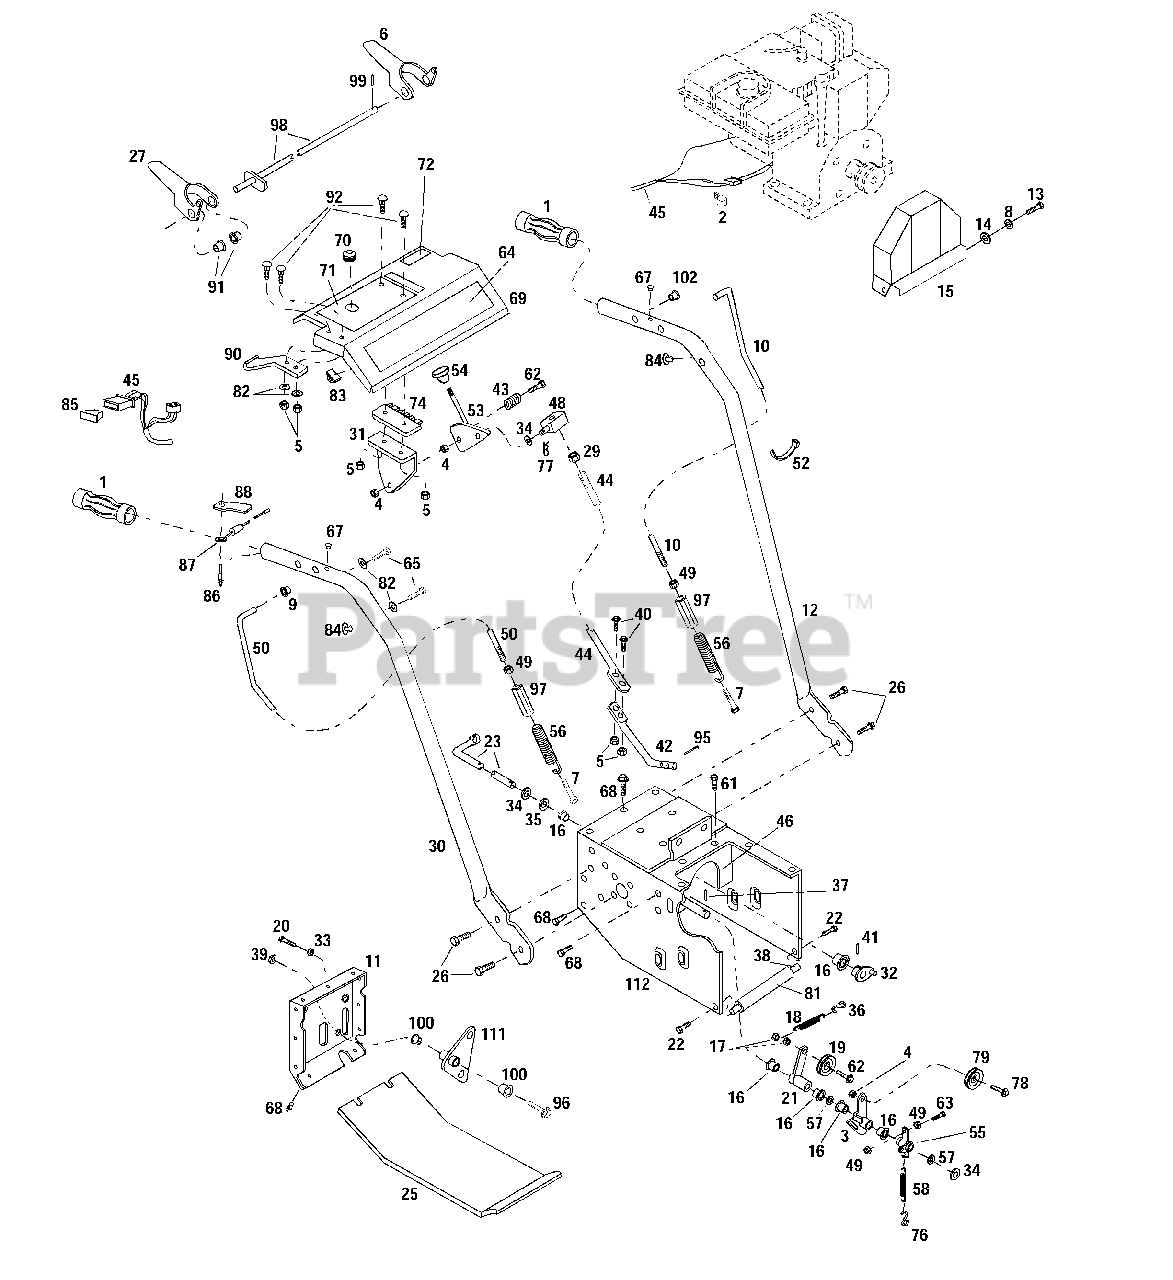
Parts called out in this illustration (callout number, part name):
1	Handle Grip
2	J-Clamp
3	Idler Arm
4	Lock Nut, 3/8-16
5	Lock Nut, 1/4-20
6	Left Control Handle
7	Fillister-Head Bolt, 5/16-18 x 1
8	Lock Washer, 5/16
9	Push Nut
10	Wheel Drive Clutch Rod
11	Back Plate
12	Left Handle Bar
13	Hex Head Bolt, 5/16-18 x 3/4
14	Flat Washer, 5/16
15	Belt Cover
17	Self-Locking Jam Nut, 3/8-16
18	Extension Spring
19	Idler Pulley
20	Flange Bolt, 5/16-18 x 1-3/4
21	Idler Arm
22	Flange Bolt, 5/16-18 x 3/4
23	Control Arm
25	Bottom Cover
26	Flange Bolt, 3/8-16 x 3/4
27	Right Control Handle
29	Hex Nut, 3/8-16
30	Right Handle Bar
31	Control Bracket
32	Control Arm
33	Jam Nut, 5/16-18
34	Flat Washer, 1/2
35	Bowed Washer
36	S-Hook
37	Cotter Pin, 3/32 x 1
38	Cross Member
39	Flange Nut, 3/8-16
40	Cap Screw, 1/4-20 x 3/4
41	Drive Pin, 1/8 x 3/4
42	Lower Control Rod
43	Compression Spring
44	Upper Control Rod
45	Wiring Harness
46	Support Assembly
48	Pivot Block
49	Hex Nut, 1/4-20
50	Auger Control Rod
52	Cable Tie
53	Shift Control Arm
55	Brake Arm
56	Extension Spring
57	Flat Washer, 1/2"
58	Extension Spring
61	Flange Bolt, 5/16-18 x 1/2
62	Hex Head Bolt, 3/8-16 x 1-3/4
63	Hex Head Cap Bolt, 1/4-20 x 1
64	Logo Decal
65	Thread-Forming Bolt, 1/4-20 x 5/8
67	Wear Button
68	Thread-Forming Bolt, 5/16-18 x 3/4
69	Console
70	Flip Grommet
71	Instructions Decal
72	Wheel Control Decal
74	Shift Quadrant
77	Cotter Spring
78	Hex Head Bolt, 3/8-16 x 2
79	Idler Pulley
81	Plastic Tubing
82	Flat Washer, 1/4
83	Cord Clip
85	Connector Body
86	Pop Rivet, 1/8
87	Resistor
88	Clamp
90	Flat Spring
91	Flange Bearing
92	Round Head Bolt, 1/4-20 x 5/8
95	Cotter Pin, 3/32 x 3/4
96	Shoulder Bolt
97	Adjusting Nut
98	Control Rod
99	Roll Pin, 1/8 x 5/8
100	Nyliner Flange Bushing
102	Flange Bearing
111	Speed Control Arm
112	Frame
